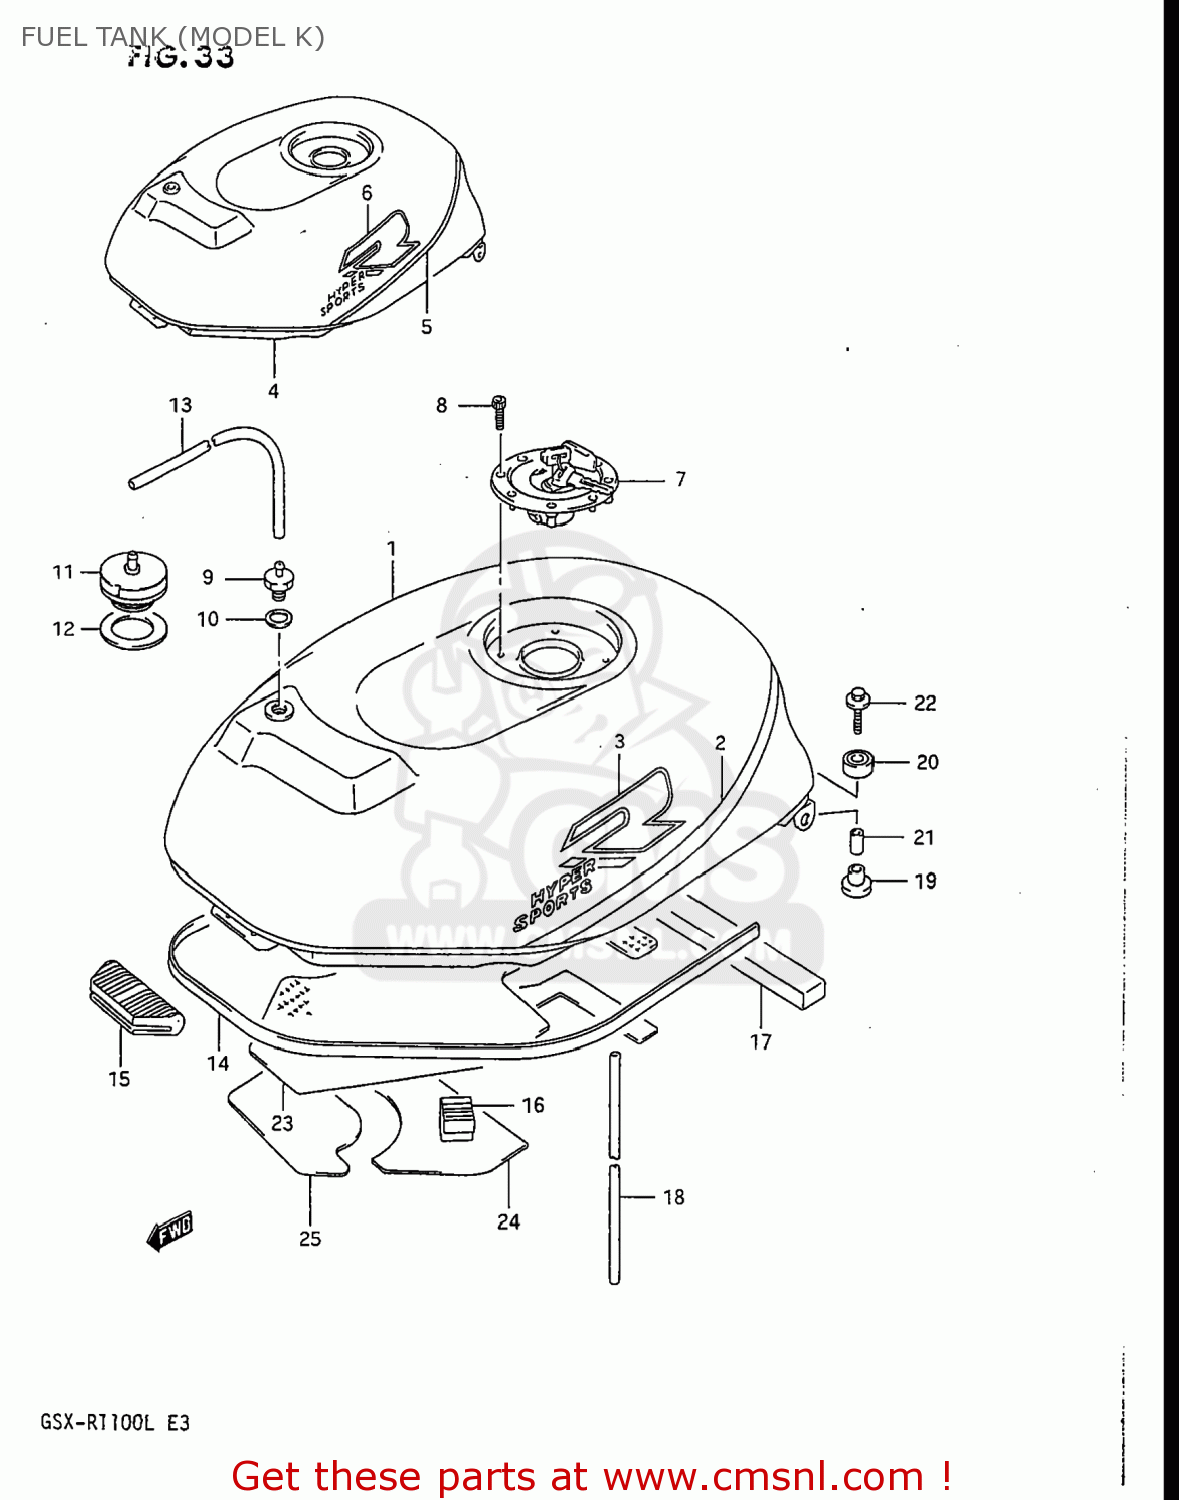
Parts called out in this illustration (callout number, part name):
1	TANK ASSEMBLY,FUEL
2	TAPE,FUEL TANK STRIPE
3	EMBLEM,FUEL TANK
4	TANK ASSEMBLY,FUEL
5	TAPE,FUEL TANK STRIPE
6	EMBLEM,FUEL TANK
7	CAP SET,FUEL TANK
8	BOLT(5X20)
9	PLUG,FUEL TANK BREATHER
10	GASKET(12.5X20X2.5) (NAS)
11	(CA) VALVE,FUEL TANK BREATHER
12	GASKET 27X40X2.5 (NAS)
13	HOSE
14	MOLDING,FUEL TANK
15	CUSHION,FUEL TANK FR
16	CUSHION,TANK,S
17	CUSHION, AIR SEAL
18	HOSE
19	CUSHION
20	CUSHION
21	SPACER
22	BOLT(6X35)
23	HEAT SHIELD,FUEL TANK
24	HEAT SHIELD,FUEL TANK IN
25	HEAT SHIELD,FUEL TANK IN
